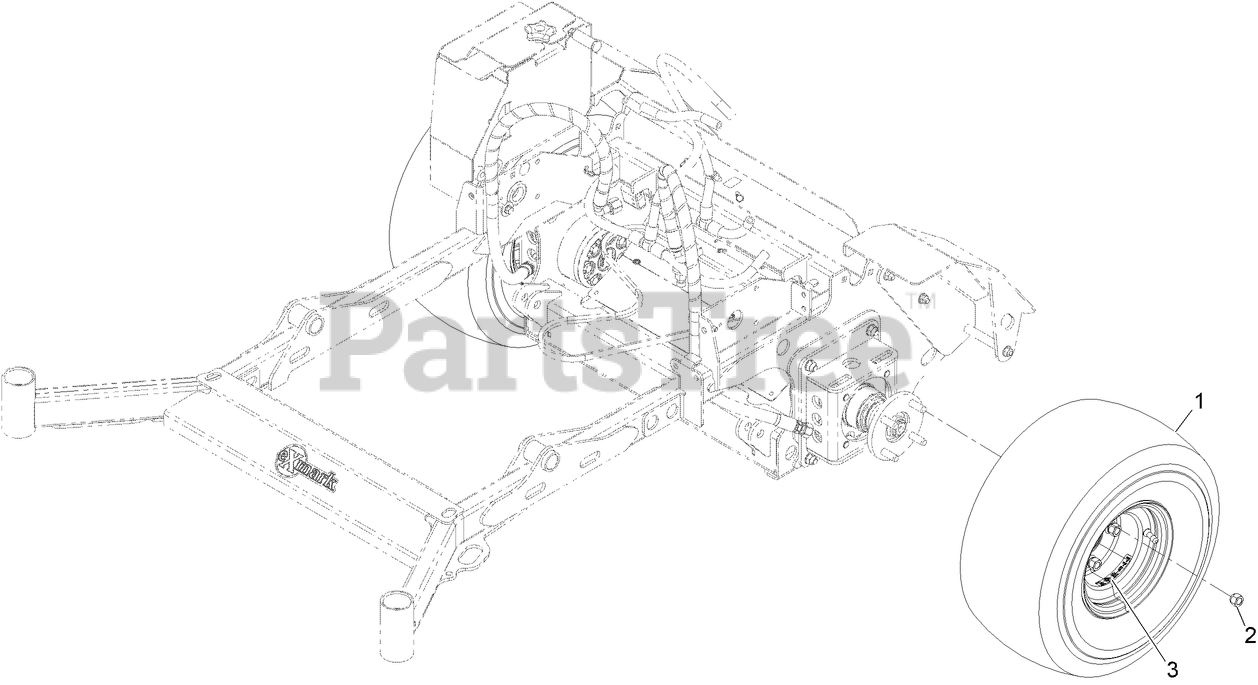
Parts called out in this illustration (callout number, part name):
1	Wheel/Tire ASM
2	NUT-LUG
3	DECAL-TORQUE, WHEEL HUB LUG
